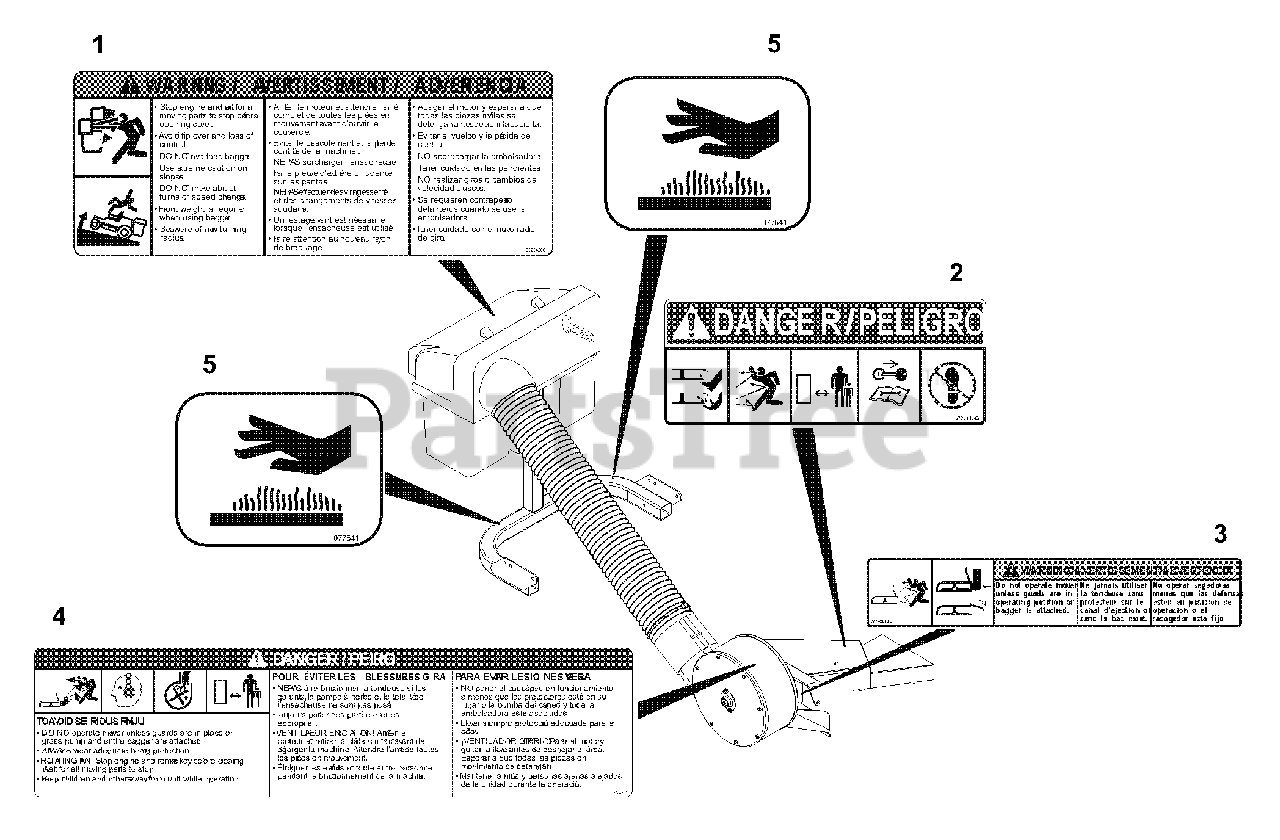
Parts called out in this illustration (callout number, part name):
1	Decal-Warning, Bagger Cover
2	Decal, Mower Pan Head Danger
3	Decal, Warning
4	Decal-Caution, Grass Pump
5	Decal, Hot Surface
